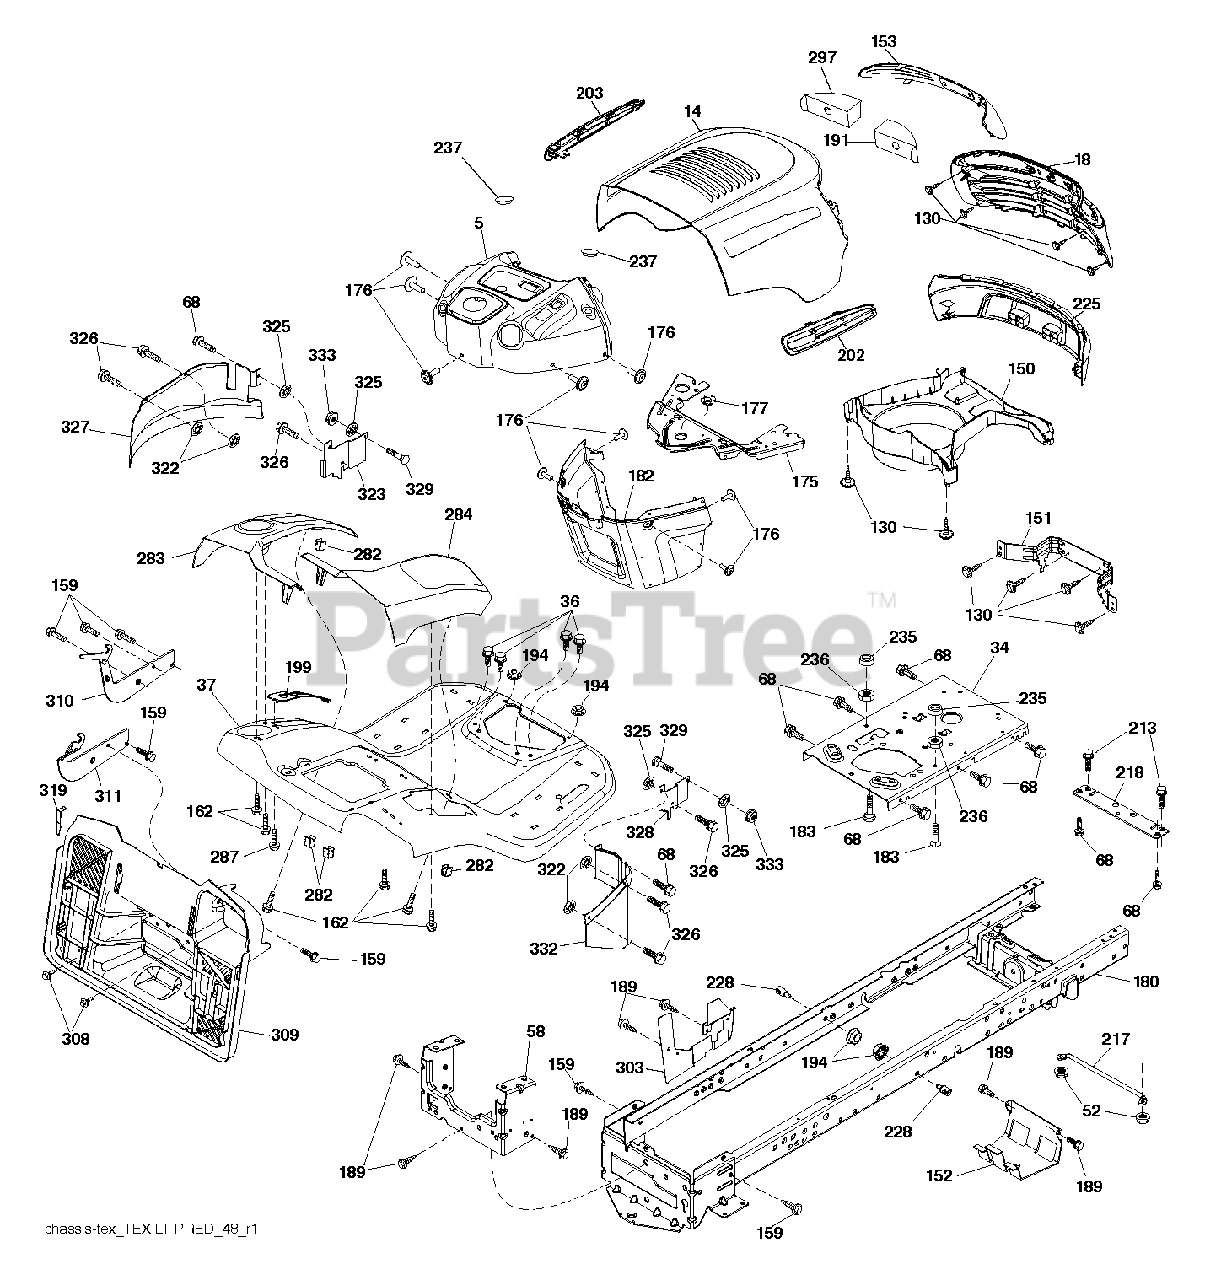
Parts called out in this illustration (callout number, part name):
34	PLATE.ENGINE.WELDED.CHASSIS
36	SCREW 5/16"
52	LOCKNUT
58	DRAWBAR UPPER 2PC SMALL FENDER
130	SCREW.#10 X 0.750.BOS THREAD
151	BRACKET.PIVOT.ALPHA.LT
152	SHIELD BROWNING
153	LENS.PREDATOR.LT
159	SCREW, 3/8-16X3/4
162	SCREW.HI-LO.CONSOLE
175	CROSSMEMBER
176	SCREW.#10-24X5/8.RN.QU
177	BUSHING STEERING
182	DASH.LWER.PREDATOR/HUSQ.LT
183	BOLT.5/16-18X1-1/4 FULL THD
189	SCREW
191	INSERT.REFLECT.PREDATOR.LT.RH
194	NUT LOCK HEX FLANGE 5/16-18
213	BOLT
217	ROD.PIVOT.HOOD
218	X-PIECE.HOOD.STOP.NON/
228	STUD.FASTNER.W/ANTI-ROTATE
235	SPACER FENDER
236	NUT.CENTERLOCK.5/16-
237	PLUG.MOUNT.CARGO.BLK
282	CLIP.RETAINER.CONSOLE.LT.HUSQ
297	REFLECTOR.INSERT.PRED.LH.LT
308	BOLT, 5/16-18 X 1 3/4
322	PALNUT 1/4
326	SCREW 14-20 X 5/8
329	BOLT
333	NUT.71038.31-18.HEX.NYLOCK
